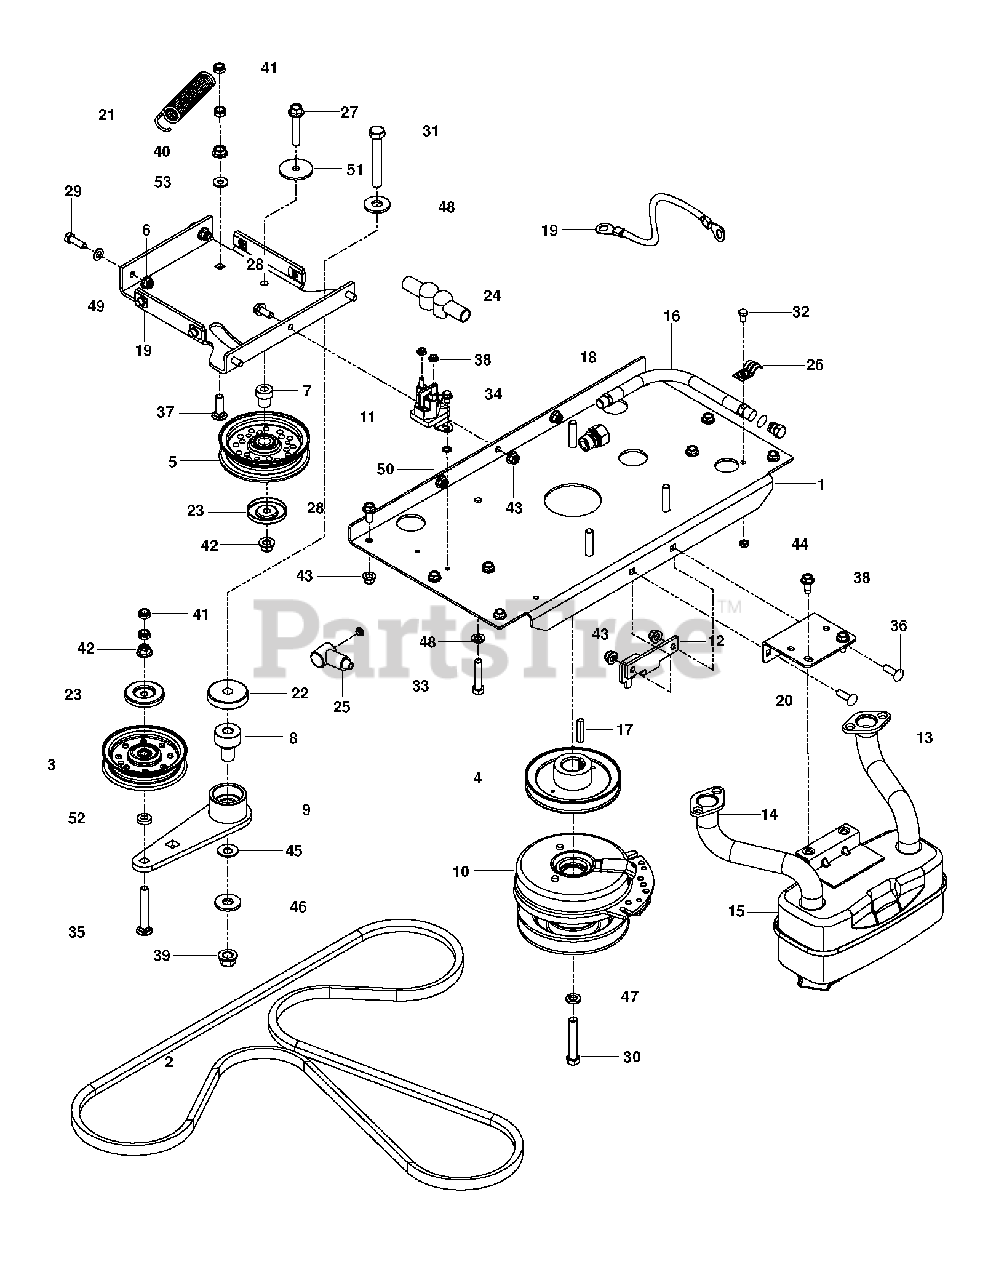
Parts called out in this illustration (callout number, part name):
1	PLATE.PNT.ENGINE.E-DIP
2	BELT, HYDRO, 3400
3	PULLEY.IDLER.FLAT.46.PR.DR.
4	PULLEY, V, 1.125 BORE
5	IDLER PULLEY
6	PLATE.PNT.IDLER.SUPPORT.E-DIP
7	PIVOT, IDLER
8	PIVOT, BEARING
9	ARM, IDLER, STEEL, W/BGS
10	CLUTCH 200 FT LB
11	SOLENOID.W/BRASS.PLUNGER
12	STOP, CLUTCH, BLACK
13	TUBE.EXHAUST.RH.FR961/FR730
14	TUBE.EXHAUST.LH.FR961/FR730
15	MUFFLER ASM TWIN
16	HOSE.ASSEMBLY.OIL.DRAIN
17	KEY, 1/4 SQ X 1 1/4
18	ADAPTER, OIL DRAIN
19	CABLE POSITIVE
20	BRKT, MUFFLER, BLK
21	SPRING, PUMP
22	SHIELD, DUST
23	DUST SHIELD
27	HHFS 3/8-16 X 2.0 GD 5
28	HHFS 5/16-18 X 3/4
29	BOLT.FIN.HEX.5/16-18UNC X 1.00
30	CLUTCH BOLT7/16-20X2.5 GR596HR
31	HCS 1/2-13 X 3-1/4 GD 5 ZD
32	BOLT
33	BOLT
34	RP_SCREW.1/4-20X3/8
35	BOLT
36	BOLT CRT
37	BOLT.3/8-14X1.25
38	SCREW
39	NUT, 1/2-13 HEX FLG NYLOC ZD
40	NUT 3/8C WHIZ
41	NUT HEX 3/8-16 NYLON, THIN
42	NUT 3/8-16 HEX FLG NYLOC ZD
43	5/16-18 NYLOC FLANGE NUT
44	JAM NUT 1/4C (2 2 PW01)
45	CONTACT BELLSPR 1/2
46	WASHER.9/16 X 1 3/8 X 12 GA.
47	WASHER 7/16 LOCK
48	LOCKWASHER
49	WASHER
50	WASHER 1/4 INT TOOTH
51	WASHER, 3/8 SPEC
52	WASHER 3/8 X 3/4 X .187 TK
53	WASHER 3/8 FLAT
